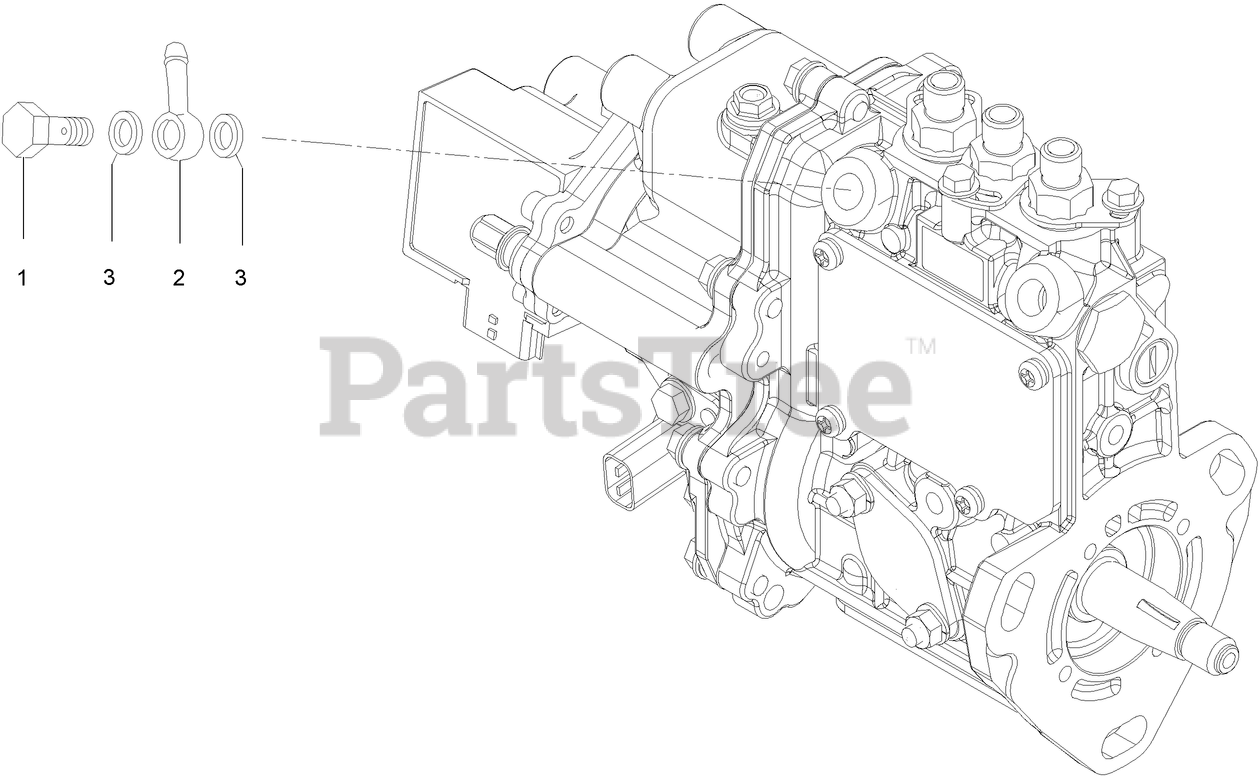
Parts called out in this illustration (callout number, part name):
1	BOLT-PIPE JOINT
2	JOINT-PIPE
3	WASHER-SEAL
